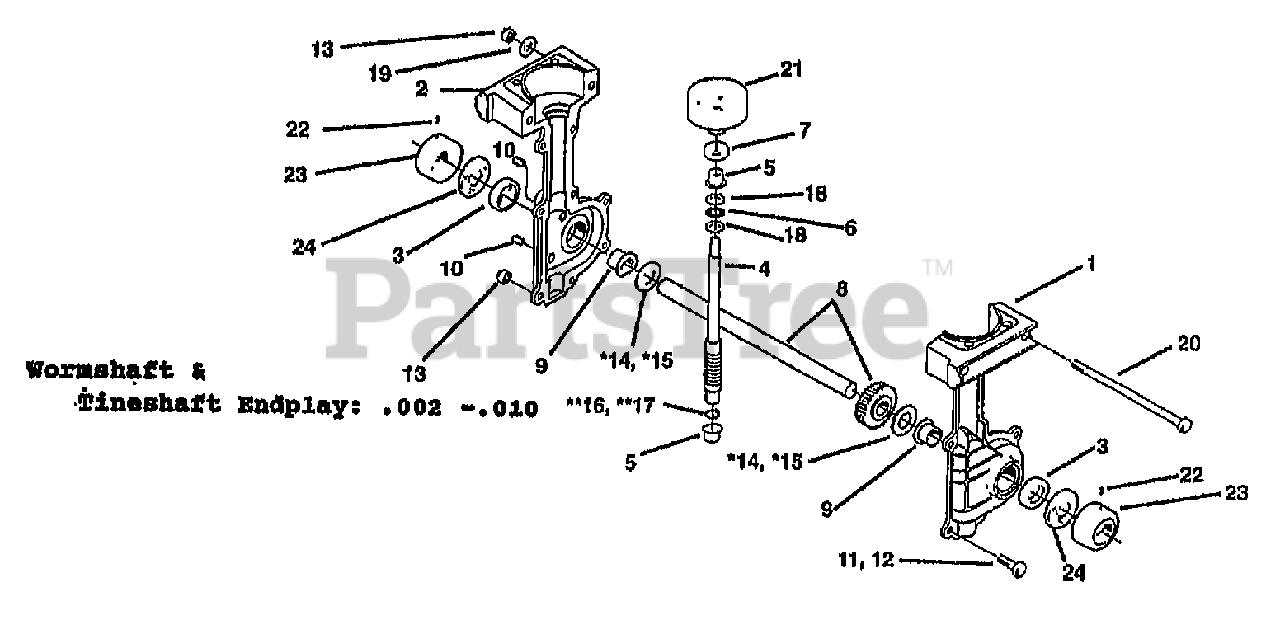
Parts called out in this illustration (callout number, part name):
1	TRANS-CASE LH PT/85023/00
2	TRANS-CASE RH PT/85024/00
3	SEAL-PINION SHAFT PT/85030/00
4	SHAFT-WORM PT/85032/00
5	BEARING-INPUT
6	BEARING-THRUST PT/85034/00
7	BEARING-BALL PT/85035/00
8	ASSM-SHAFT OUTPUT AS/85037/00
9	BUSHING-1.25X.755X.73
10	PLUG-PIPE 1/8 NPT
11	SCREW 1/4-20 X .875 (FIVE LOCATIONS ON TRANSMISSION CASE)
12	SCREW 1/4-20X1.125 (THREE LOCATIONS ON TRANSMISSION CASE)
13	NUT-LK 1/4-20
14	WASHER-THRUST .775X.05 (.050")
15	WASHER-THRUST .775X.05 (.040")
16	WASHER-THRUST .505X.02 (.020")
17	WASHER-.76X.5X.04 THRUST (.025")
18	WASHER-THRUST .92X.5X.06
19	WASHER-.75X.312X.065 ZP
20	SCR-HH 1/4-20X5
21	CLUTCH-DRUM & HUB
22	SCR M10-32X.25
23	KIT-DUST CAP
24	WASHER-FELT 1.5X.72X.13
